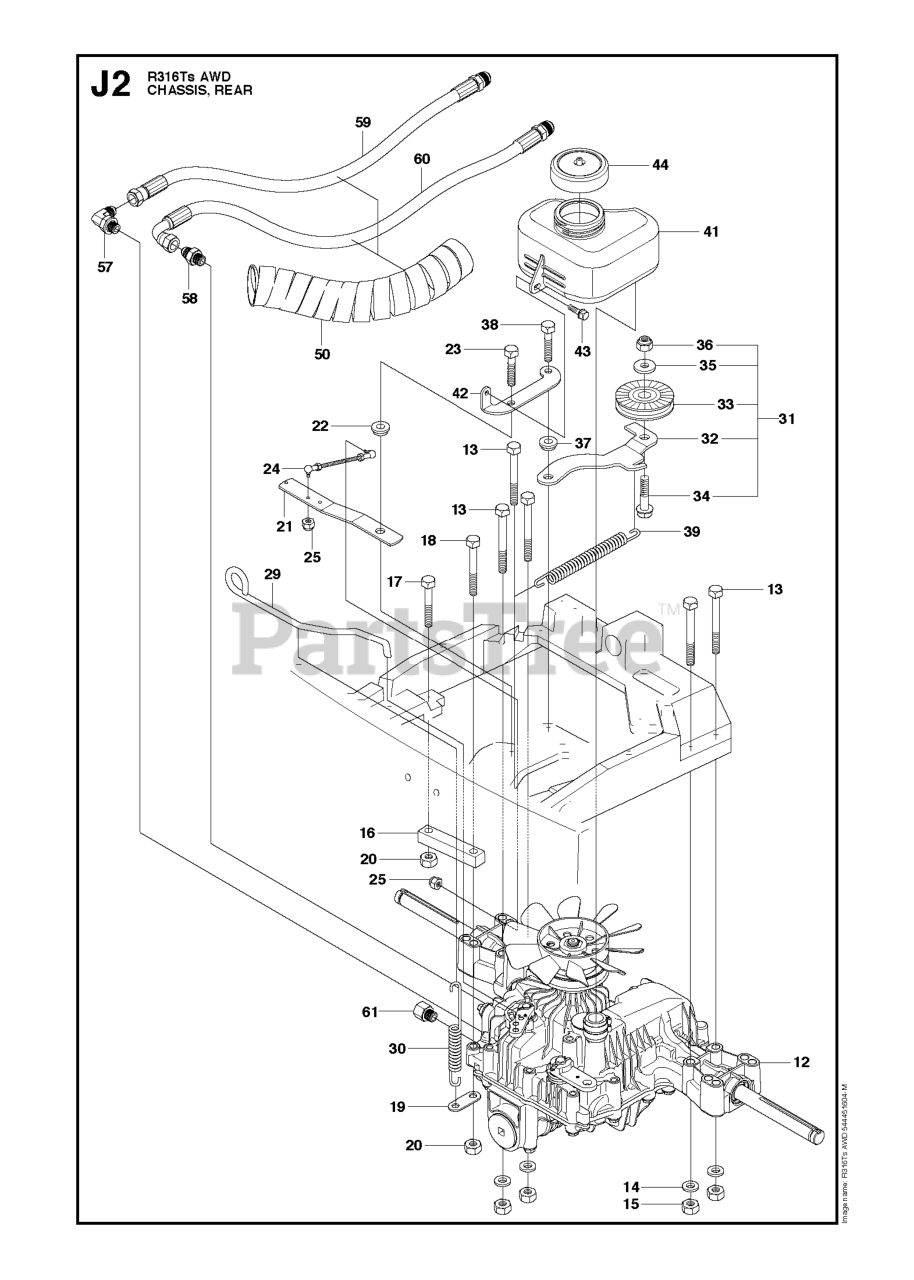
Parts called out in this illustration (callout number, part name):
14	WASHER BRB 8.4X17
15	NUT
20	NUT
22	WASHER
25	LOCKNUT M5
32	TENSIONER
34	SCREW
36	LOCKNUT M8
37	WASHER
39	SPRING
41	TANK
50	HOSE GUARD D=43 L=400
